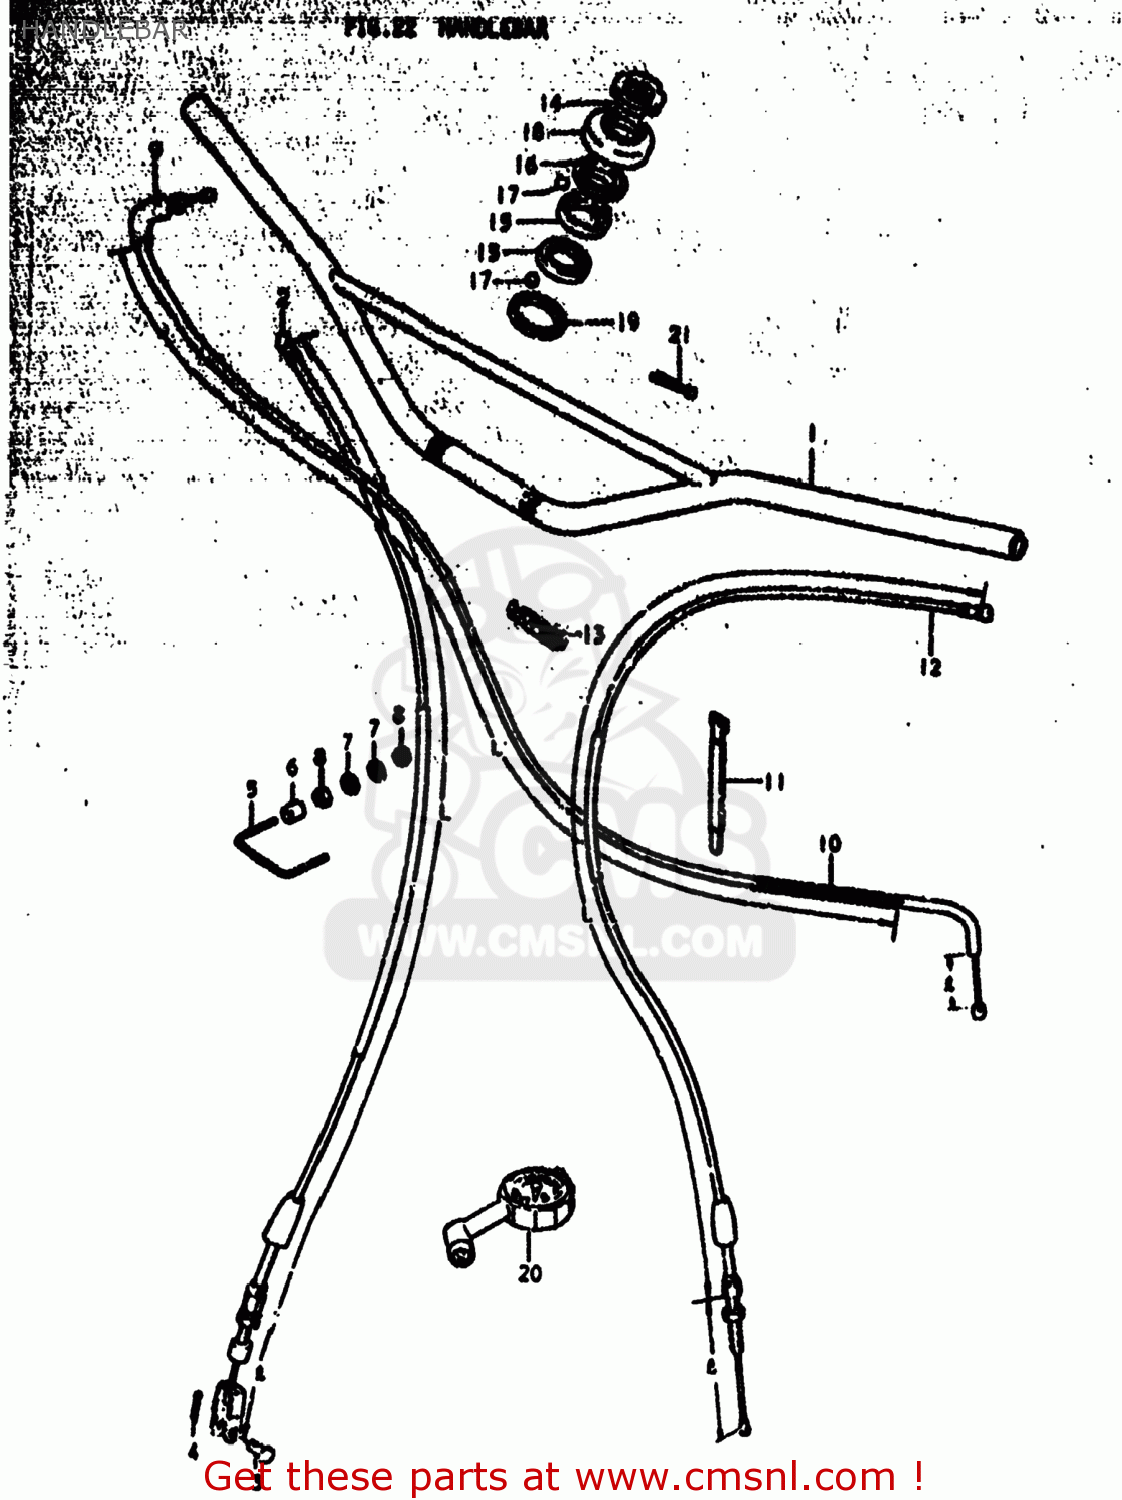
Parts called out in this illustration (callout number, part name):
1	HANDLEBAR
2	CABLE ASSEMBLY,FRONT BRAKE
3	PIN(L:17.5)
4	PIN
5	CLAMP,CABLE
6	BUSHING
7	WASHER
8	NUT 3MM
9	CABLE ASSEMBLY,THROTTLE
10	PROTECTOR,CABLE
11	CLAMP
12	CABLE ASSY,CLUTCH
13	CLAMP L:35
14	NUT,STEERING STEM
15	RACE,STEERING,INNER,UPPER
16	RACE,STEERING,OUTER,UPPER
17	BALL
18	SEAL,STEERING UPR DUST
19	DUST SEAL,STEERING HEAD
20	GAUGE ASSY,AIR PRESSURE
21	PIN 20X20
